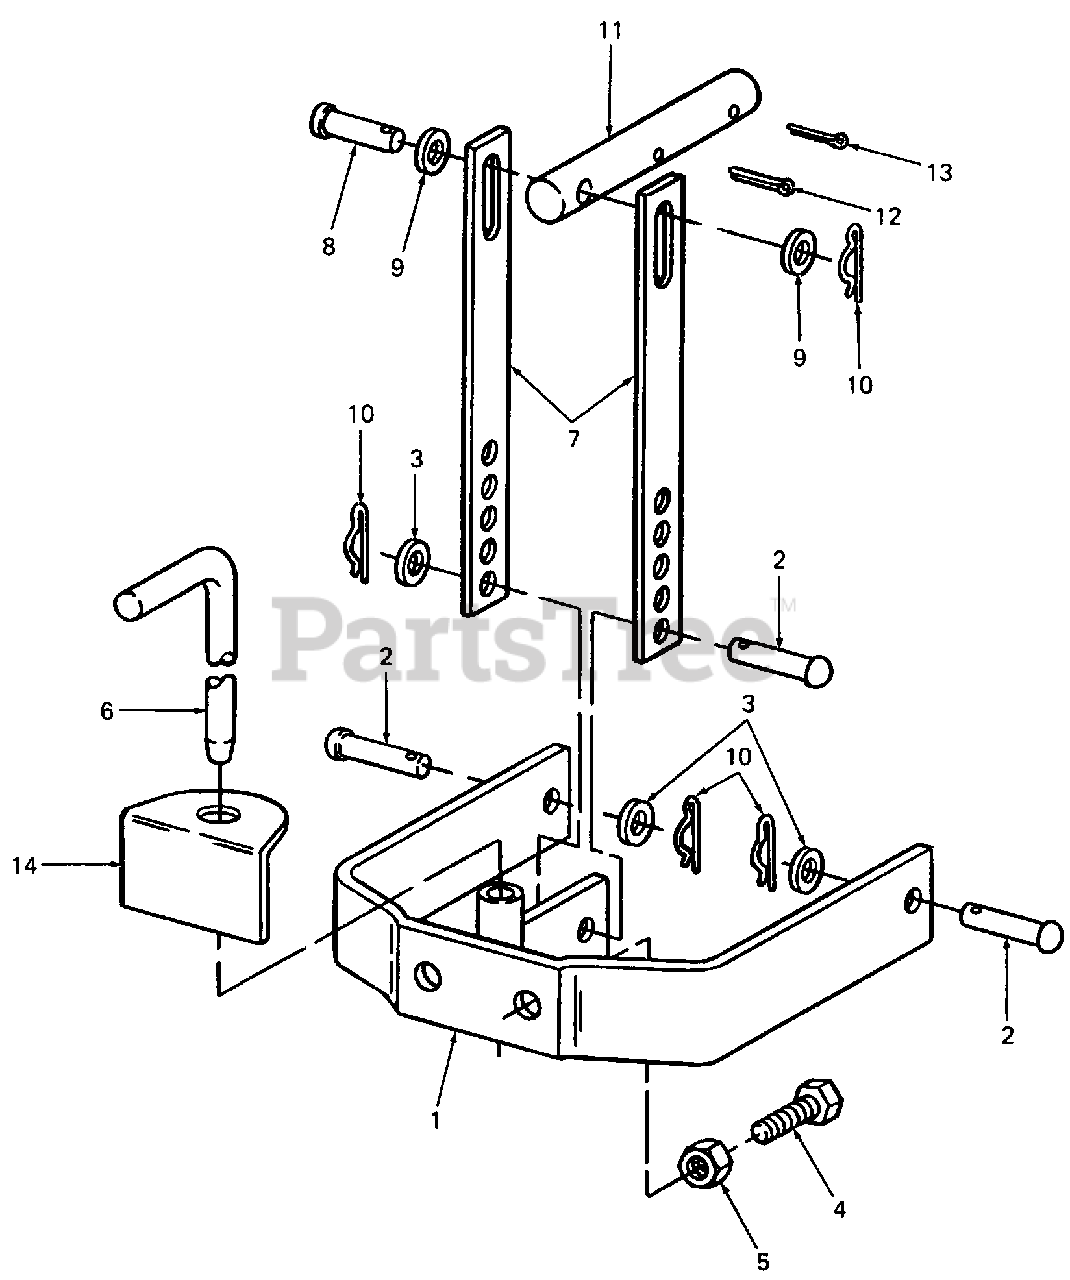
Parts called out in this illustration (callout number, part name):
1	Yoke Assy, Hitch
2	Pin, Clevis, 1/2 X 1.5 Lg
3	Washer, Flat, .50 X 1.00 X .060 Thk
4	Screw, Hex Cap, 5/8-11 X 2.0 Lg
5	Nut, Hex Jam, 5/8-11
6	Pin, Hitch
7	Strap, Lift
8	Pin, Clevis, 1/2 X 2.5 Lg
9	Washer, Flat, .50 X 1.00 X .060 Thk
10	Pin, Internal Cotter
11	Rod, Lift
12	Pin, Cotter, 3/16 Dia X 2.0 Lg
13	Pin, Cotter, 1/8 Dia X 1.5 Lg
14	Plate, Stabilizer
